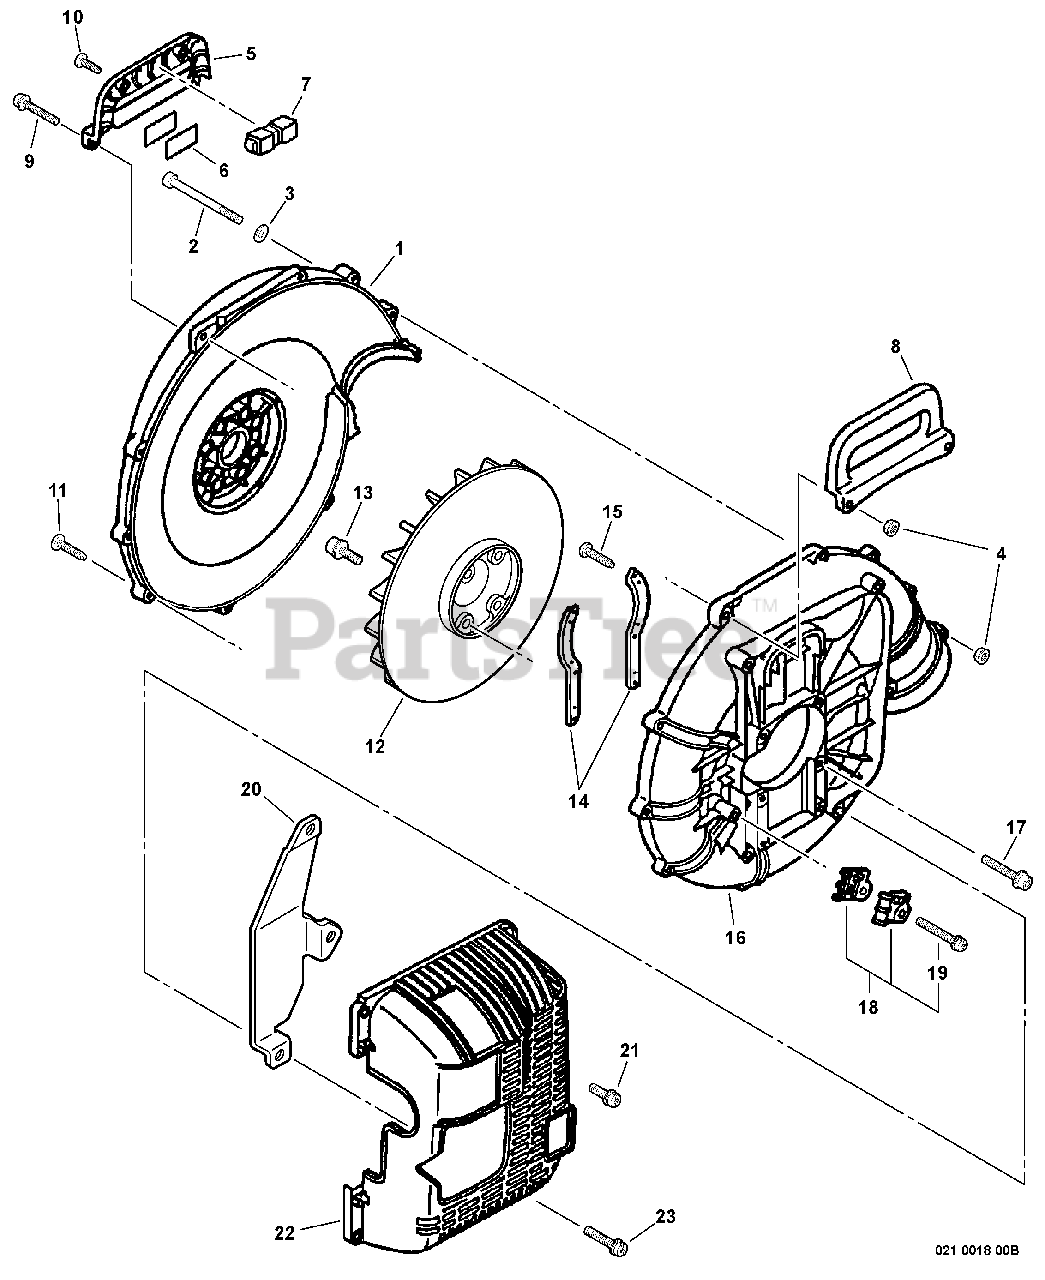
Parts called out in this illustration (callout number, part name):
1	COVER, FAN - INNER
2	SCREW - 5X60
3	WASHER - 5
4	NUT - 5 -- FLANGE
5	HANDLE - INNER -- GRAY
7	WEIGHT, HANDLE
8	HANDLE - OUTER -- GRAY
9	SCREW - 5X45
10	SCREW - 5X16 -- TAPPING
11	SCREW - 5X30
12	FAN
13	SCREW - 5X20
14	BRACKET, ENGINE
15	SCREW - 3X12 -- TAPPING
16	COVER, FAN - OUTER
17	SCREW - 5X32
18	CABLE HOLDER KIT
19	SCREW - 5X25
20	INSULATOR
21	SCREW - 5X10
22	COVER, ENGINE
23	SCREW - 5X18
